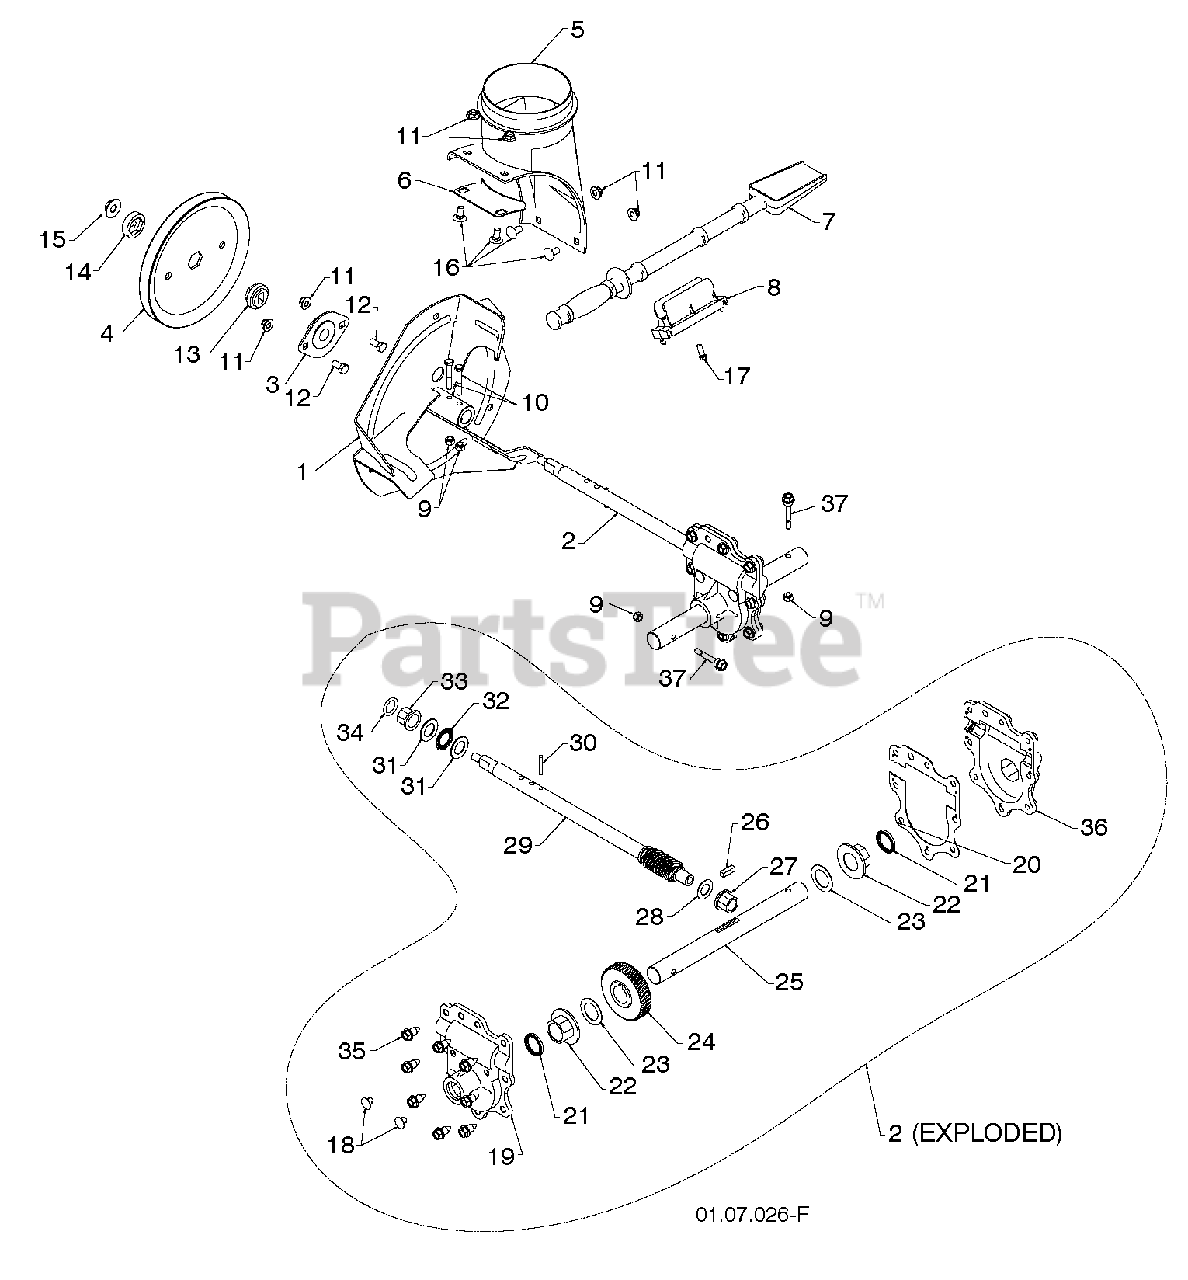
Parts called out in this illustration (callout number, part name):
1	IMPELLER ASSY
2	GEARBOX.ASM.AUGER.D-SHAFT
3	BEARING FLANGE
4	PULLEY.FLANGE.IMPELLER
5	BASE.DISCHARGE.CHUTE
6	BRACKET, CORNER DISCHARGE
7	CLEAN OUT TOOL
8	CLIP.CLEANOUT.TOOL
9	LOCKNUT.NYLOC.1/4-20
10	SCREW.HEX.HD1/4-20X
11	NUTNYLOK.FLRANGE.5/16-18
12	BOLT, HEX HEAD 5/16-18
13	HUB.IMP.PULLEY.D-SHAFT
14	SLEEVE.IMP.PULLEY.D-SHAFT
15	NUT
16	BOLT.CARRIAGE.5/16-18X
17	SCREW.HWH.13-16-5.8.BZP
18	CASE PLUG
19	GEAR.BOX.COVER.RIGHT.SIDE
20	GASKET.GEAR.BOX
21	OIL SEAL
22	FLANGE BUSHING-1"
23	WASHER TRUST 1"
24	WORM GEAR
25	AUGER SHAFT
26	KEY, SQUARE 1/4 X .875
27	FLANGE BUSHING-5/8
28	WASHER, THRUST 5/8
29	SHAFT.IMPELLER.D-SHAFT
30	PIN, ROLL 3/16 X 1-1/8
31	WASHER, THRUST 3/4
32	BEARING TRUST 3/4 NTA-1220
33	BUSHING, FLANGE 3/4
35	HEX SCREW-5/16 X 3/4
36	GEAR.BOX.COVER.LEFT.SIDE
37	BOLT.SHOULDER.SHEAR.1/4-20.
